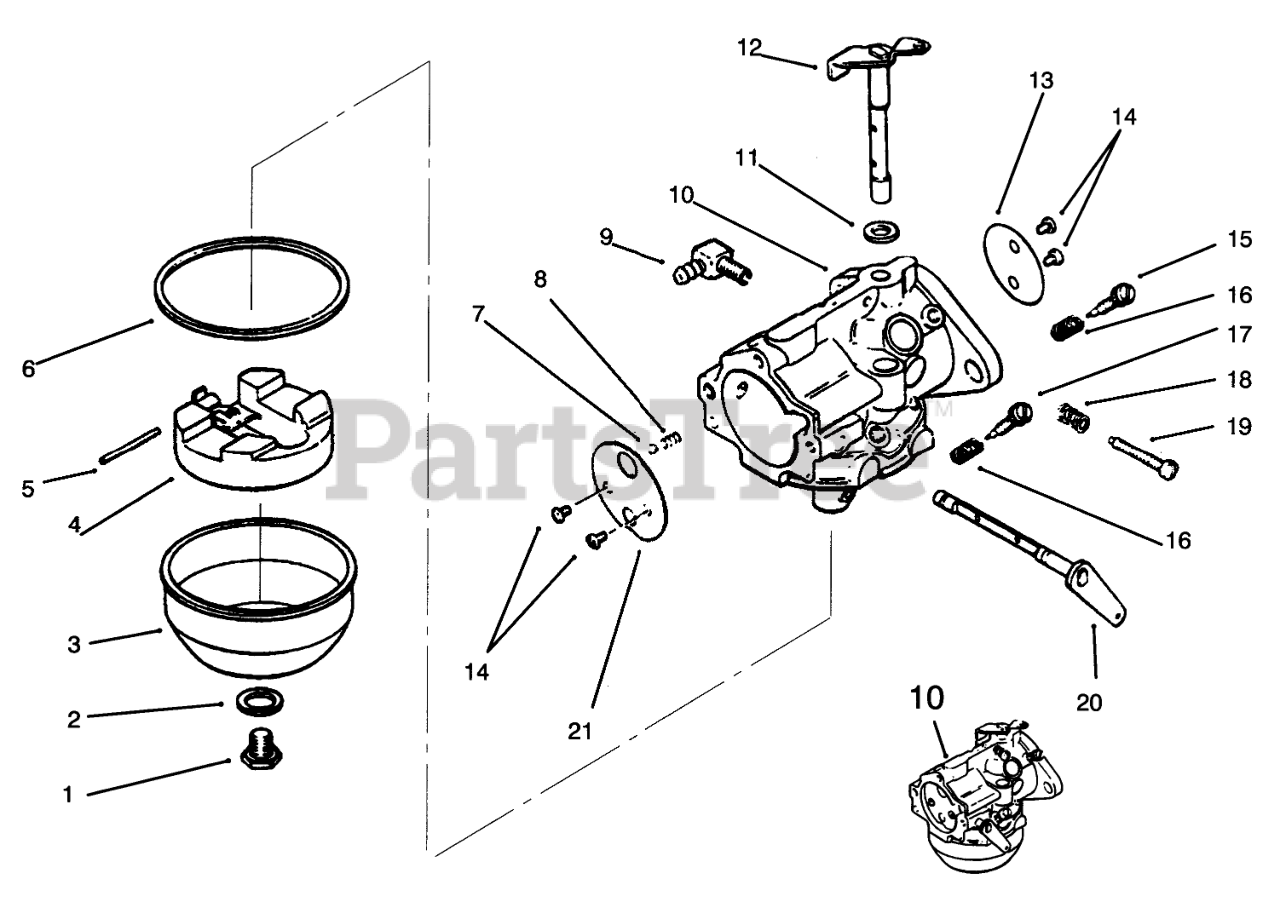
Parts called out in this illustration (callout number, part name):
1	Screw
2	Gasket
3	Bowl-Fuel
4	Kit-Float (Incl. Ref.#5)
5	Pin-Float
6	Gasket
8	Spring
9	Connector 90 Deg.
10	Carburetor Assembly(Complete)
11	Seal ASM
12	Shaft w/Lever & Seal(Incl. Ref# 11)
13	Plate-Throttle
14	Screw
15	Idle Fuel Adj. Needle
16	Spacer
17	Main-Needle
18	Adj. Spring
19	Idle Speed Adj. Screw
20	Choke Shaft
21	Choke Plate
